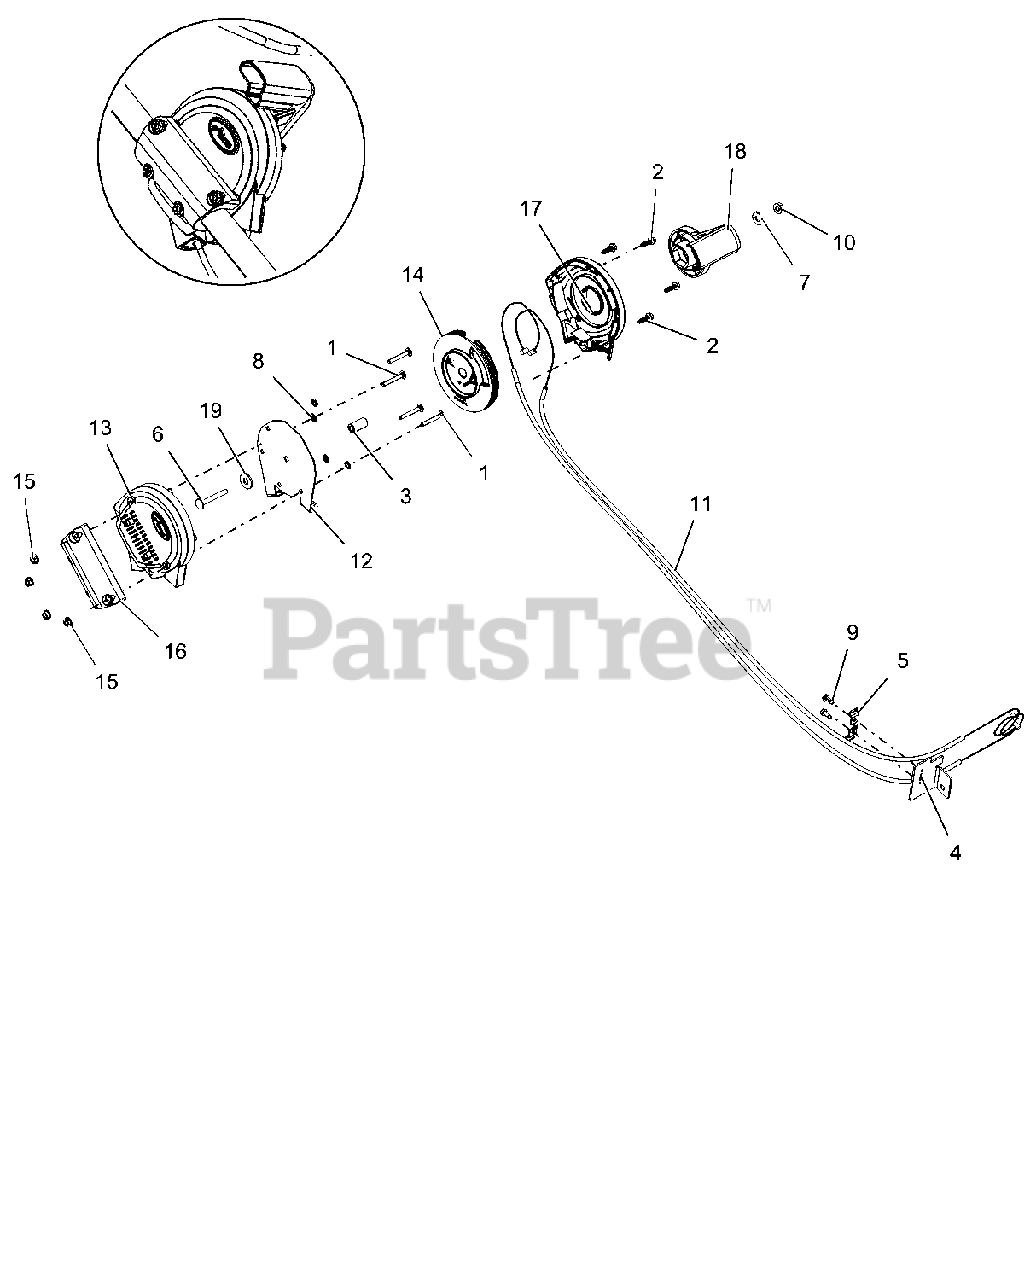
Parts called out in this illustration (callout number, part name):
1	@BLT-RDHDSQNK 10-24X1.50 G2 YZ
2	SCR-TAP #12X.75 BOSS INDHXHD
3	BSHG, SLV .265X.505X.995
4	BRKT, CABLE ANCHOR
6	@BLT-RDHDSQNK .25-20X2.00 G5YZ
7	@WSHR-FL-STL.312X.734X.065 YWZ
8	NUT-PUSH-BOLT-RET #10
9	@SCR-TAP 10-24X.50 HWH TR YWZC
10	@NUT-LK-TOP-FLG .25-20 YWZC
11	CABLE, CHUTE
12	FRAME, REMOTE CHUTE CONTROL
13	REMOTE HOUSING, RH
14	PULLEY, 4.25" POLY
15	@NUT-LK-TOP-FLG 10-24 YWZC
16	REMOTE, BRKT
17	REMOTE HOUSING, LH
18	REMOTE HANDLE
19	@WSHR-FL-STL.38X.875X.083 YWZC
